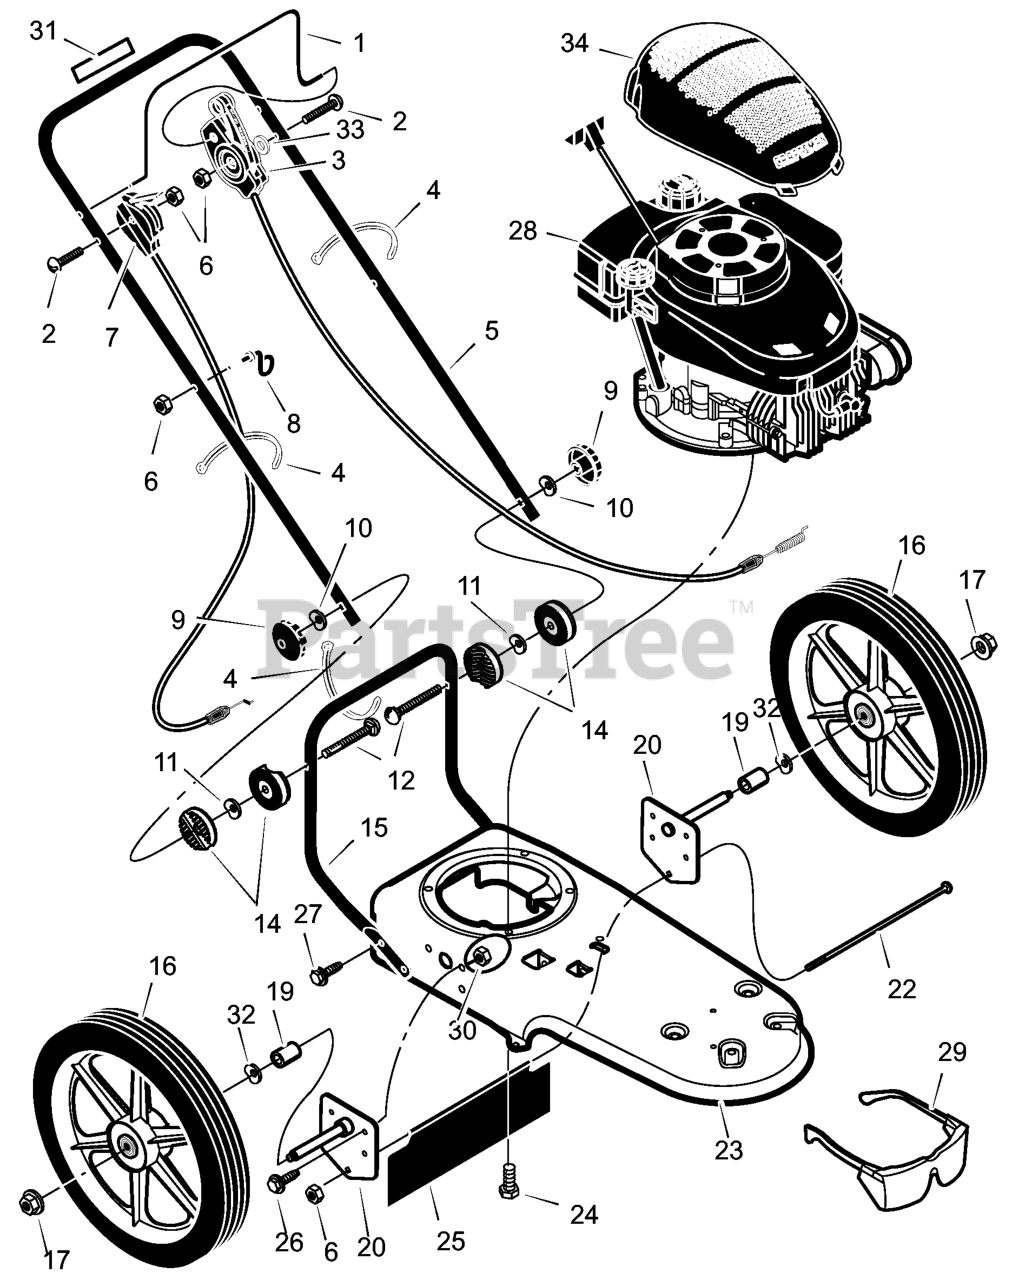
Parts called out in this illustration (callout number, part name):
1	LEVER, Stop
3	CABLE, Control Latching
4	TIE, Cable
5	HANDLEBAR
7	CONTROL, Throttle
8	GUIDE, Rope
9	KNOB, Handlebar
11	WASHER, Spring
14	PIVOT, Handlebar
15	HANDLEBAR, Lower
16	WHEEL & TIRE
17	NUT, Axle
18	WASHER
20	ASSEMBLY, Axle & Bracket
22	BOLT, Carriage
25	SHIELD, Trailing
28	Engine
29	PROTECTION, Eye
31	DECAL, Engine Stop
32	WASHER, Spring
33	SPACER, PM .26x.5x.2
34	Shroud, Engine
